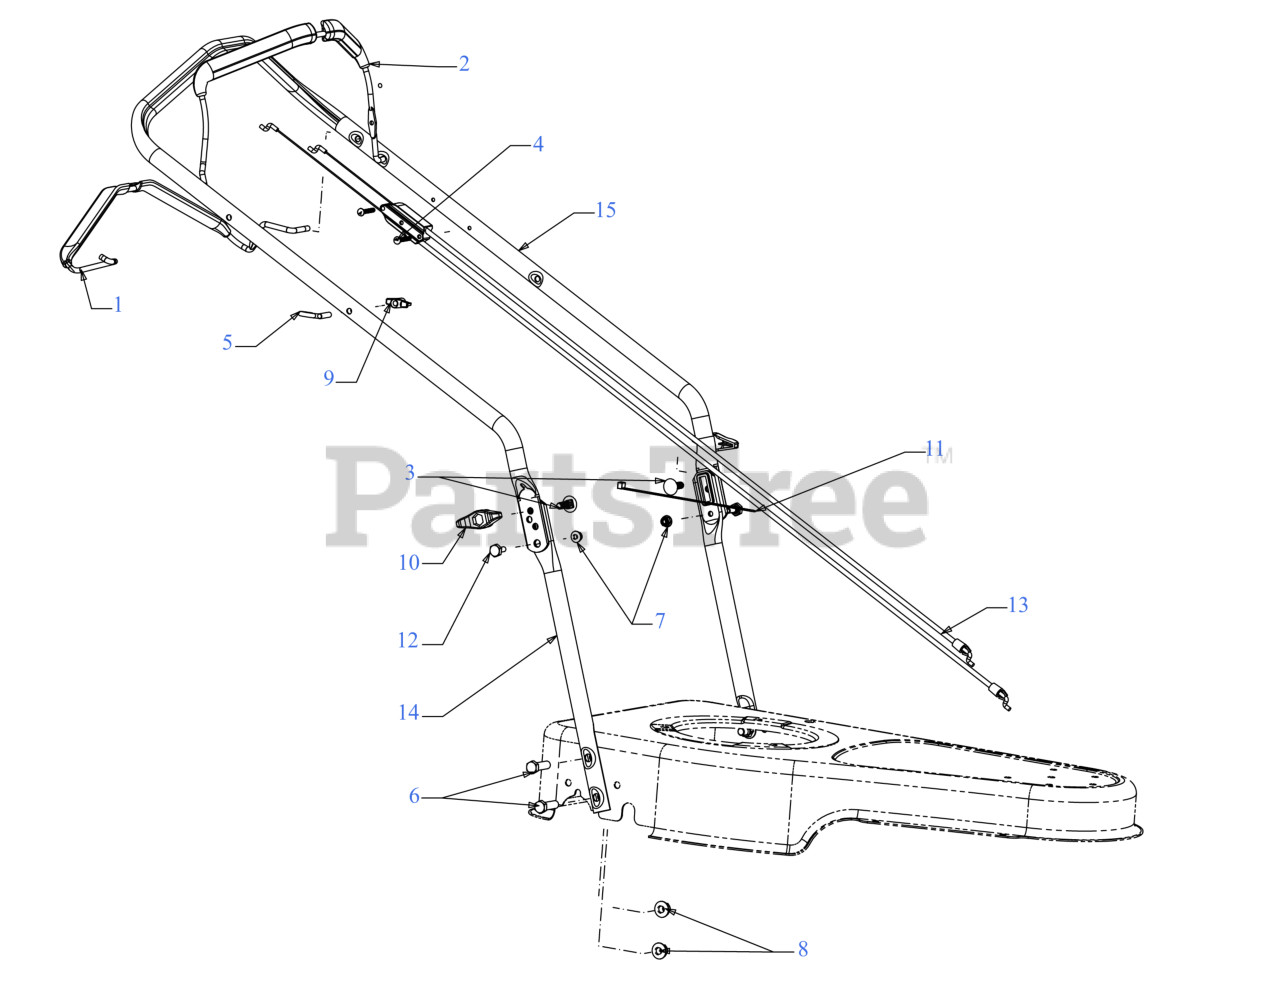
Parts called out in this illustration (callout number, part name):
1	DRIVE BAIL
2	OPERATOR BAIL ASSEMBLY
3	SCREW 5/16-18 x 1.00 GR5
4	SCREW-PANPHIL TAP 10-16 x 1.25
5	EYEBOLT 1/4-20
6	SCREW 3/8-16 x 1.25 GR5
7	FLANGE LOCK NUT
9	HANDLE KNOB
10	WING KNOB 5/16-18
11	7" CABLE TIE
12	SHOULDER SCREW
13	TRIMMER CABLE
15	UPPER HANDLE ERGO
